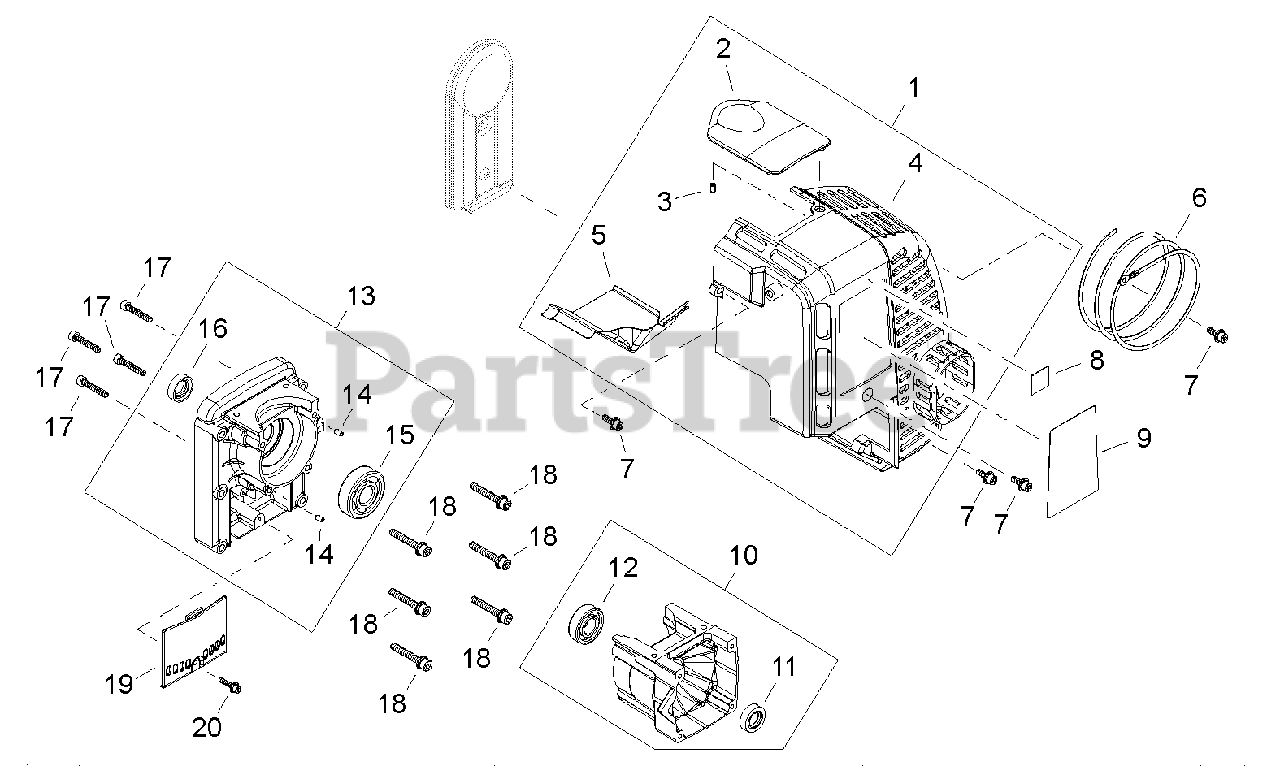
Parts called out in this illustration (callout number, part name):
1	ENGINE COVER ASSY
2	COVER, SPARK PLUG
3	PIN - 4X8
4	COVER, ENGINE
5	SHIELD, EXHAUST
6	LEAD - ANTI-STATIC
7	SCREW - 5X16
8	LABEL - CAUTION
9	LABEL - MODEL EB8520
10	CRANKCASE ASSY - FRONT
11	SEAL, OIL
12	BEARING, BALL - 6202C3
13	CRANKCASE ASSY - FRONT
14	PIN - LOCATING
15	BEARING, BALL - 6203C3
16	SEAL, OIL
17	SCREW - 5X30
18	SCREW - 6X40
19	IGNITION COIL COVER
20	SCREW - 4X20
